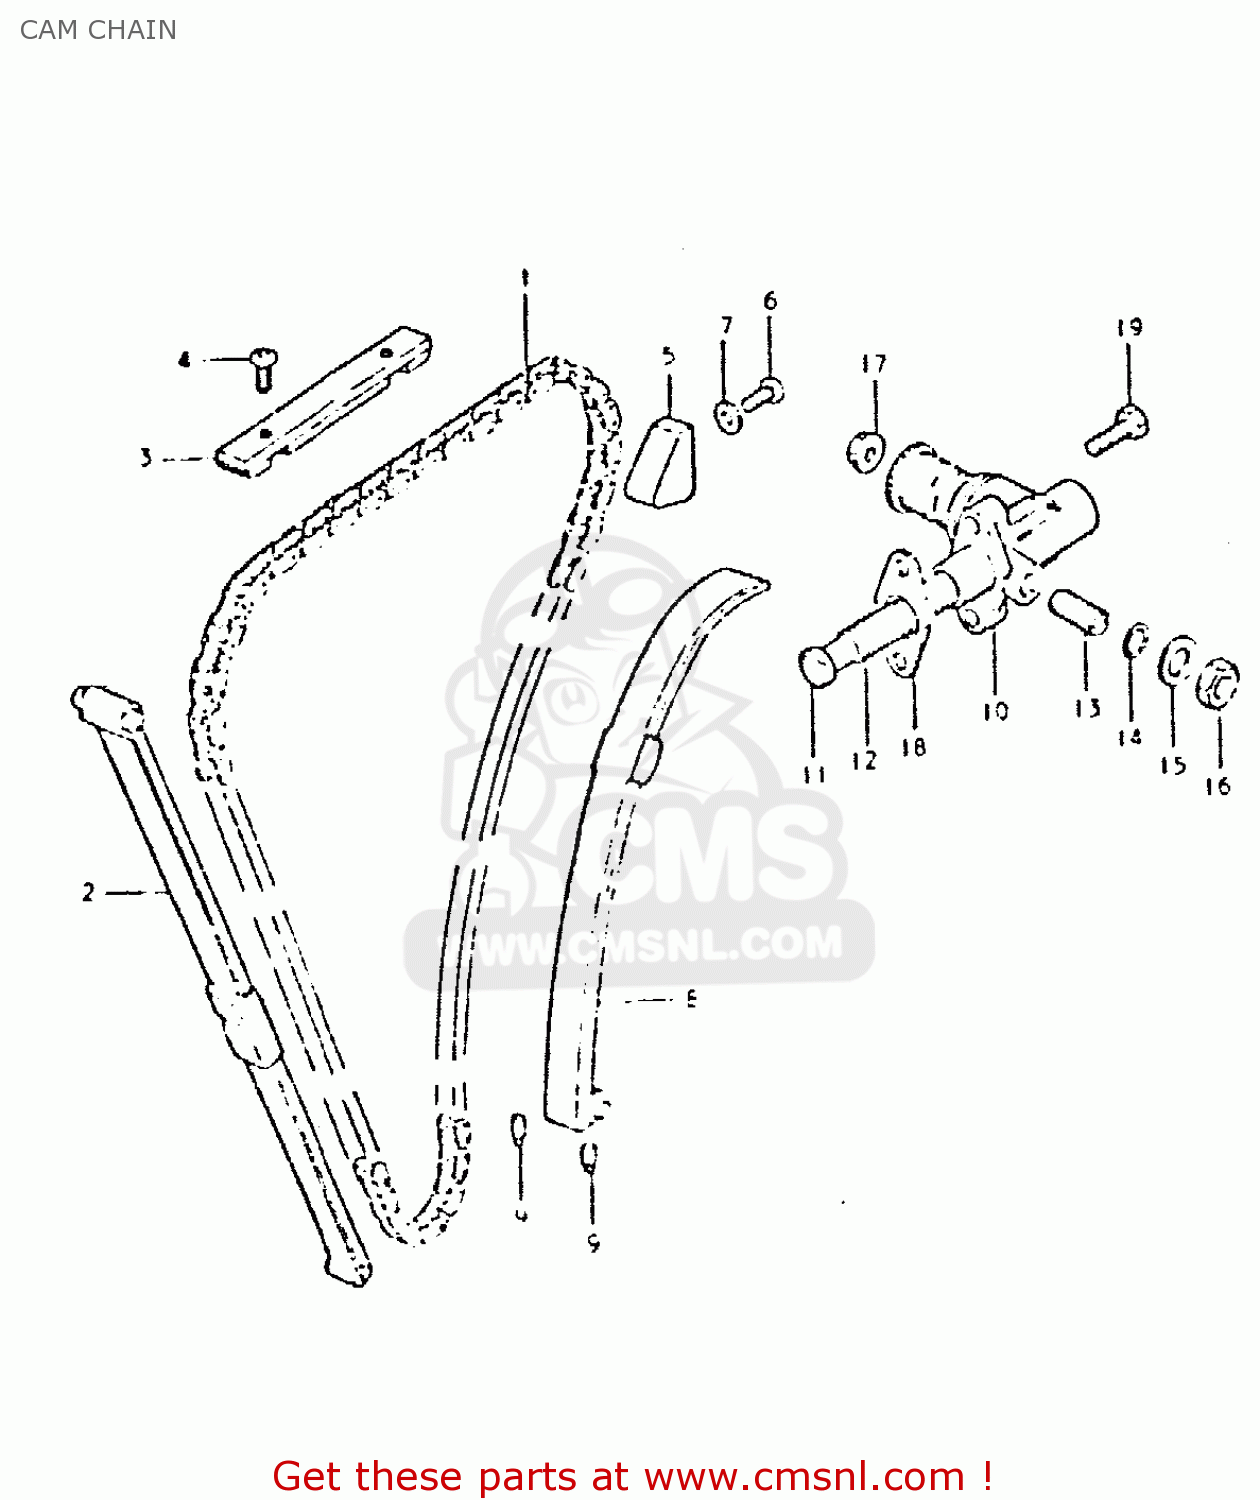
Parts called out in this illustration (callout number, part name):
1	CHAIN,CAMSHAFT DRIVE(120L)
2	GUIDE, CAM CHAIN NO.1
3	GUIDE,CAM CHAIN NO.3
4	SCREW
5	GUIDE,CAM CHAIN
6	SCREW 6X12
7	GASKET (NAS)
8	TENSIONER,CAM CHAIN
9	CUSHION,CAM CHAIN TENSIONER
10	ADJUSTER ASSEMBLY,TENSIONER
11	ROD,PUSH
12	SPRING
13	SCREW
14	O-RING
15	WASHER
16	NUT
17	NUT
18	GASKET,TENSIONER ADJUSTER (MCA)
19	SCREW (6X25)
